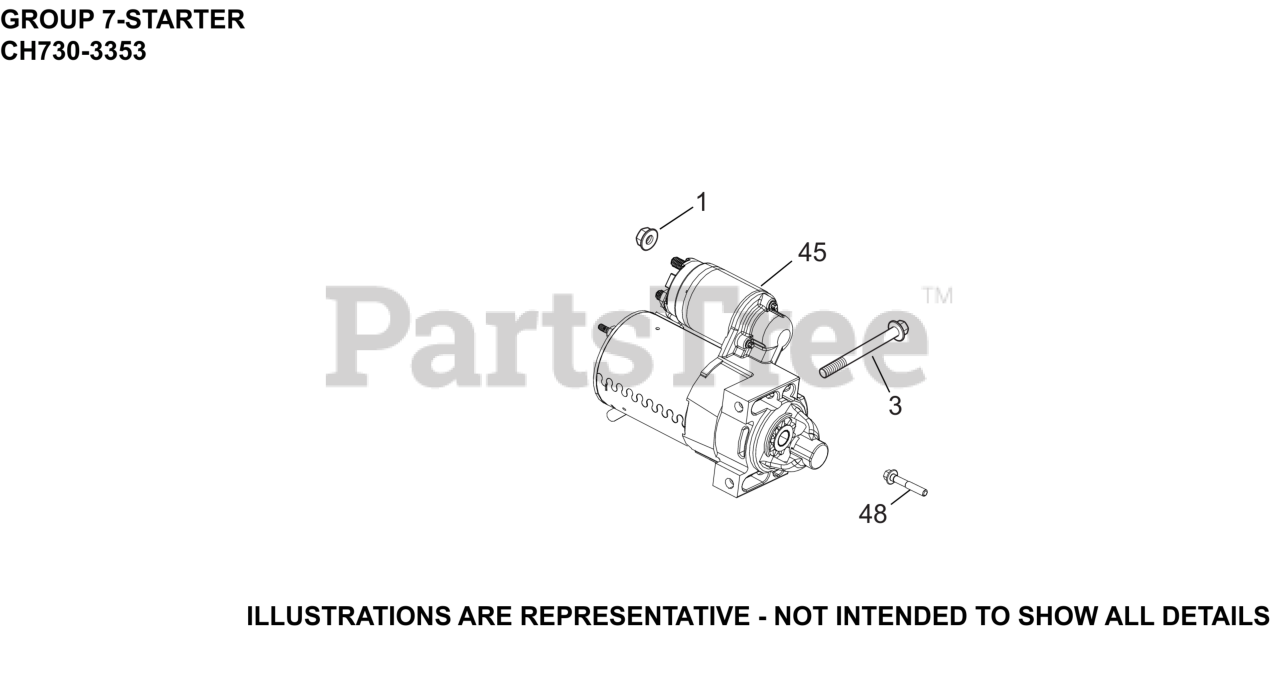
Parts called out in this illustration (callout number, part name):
1	NUT, FLG M8X1.25
3	SCREW, FLG M8X1.25X80
45	STARTER, SOLENOID SHIFT (25 098 09-S)
48	SCREW, HEX FLANGE
